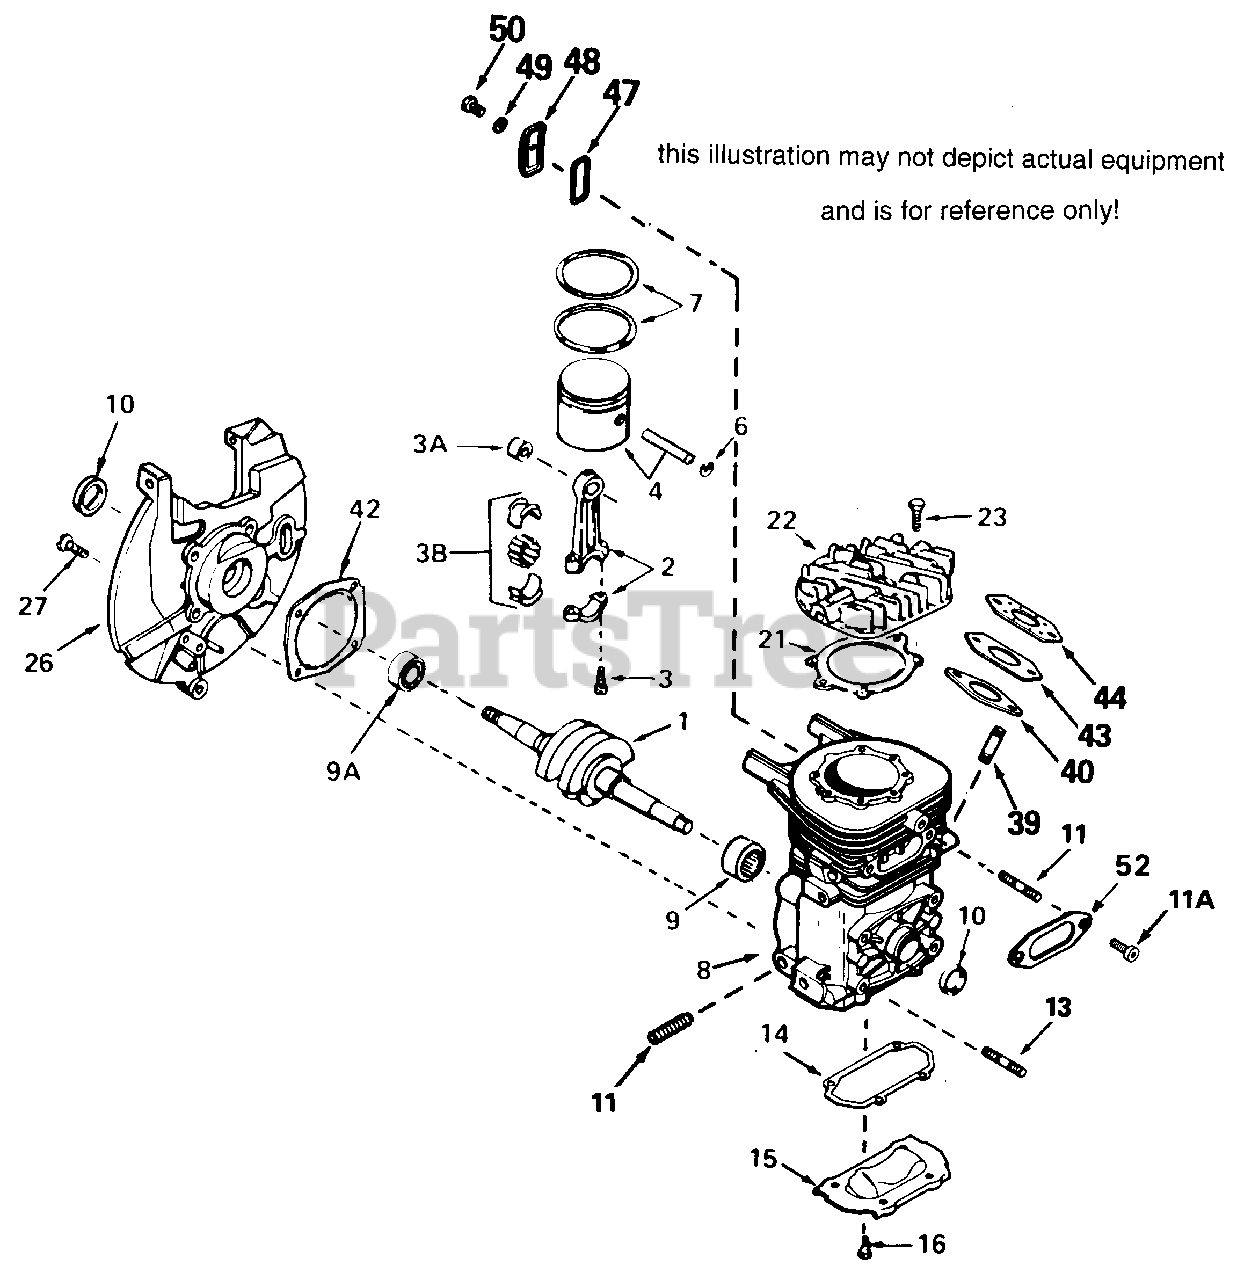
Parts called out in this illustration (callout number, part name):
1	"Crankshaft
2	Rod Assy., Connecting Incl. 3, 3A &3B
3	Screw, Connecting rod
3A	Bearing, Cartridge
3B	Bearing & Liner Set, Needle
4	Piston & Pin Assy. (Incl. 6)
6	Ring, Piston pin retaining
7	Ring Set, Piston
8	Cylinder Order SB if replacement isre q.
9	Bearing, Needle
9A	Bearing, Ball
10	Seal, Crankshaft
14	Gasket, Cover
15	Plate, Cover
16	Screw, Int. Torx T-25, 10-24 x 1/2"
21	Gasket, Cylinder head
22	Cylinder Head
23	Screw, Torx T-30, 1/4-20 x 3/4"
26	Blower Housing Base (Incl. 75)
27	Screw, Torx T-30, 1/4-20 x 5/8"
39	Stud, Carburetor
40	Gasket, Carburetor
42	Gasket, Housing base
44	Gasket, Carburetor
52	Gasket, Muffler
